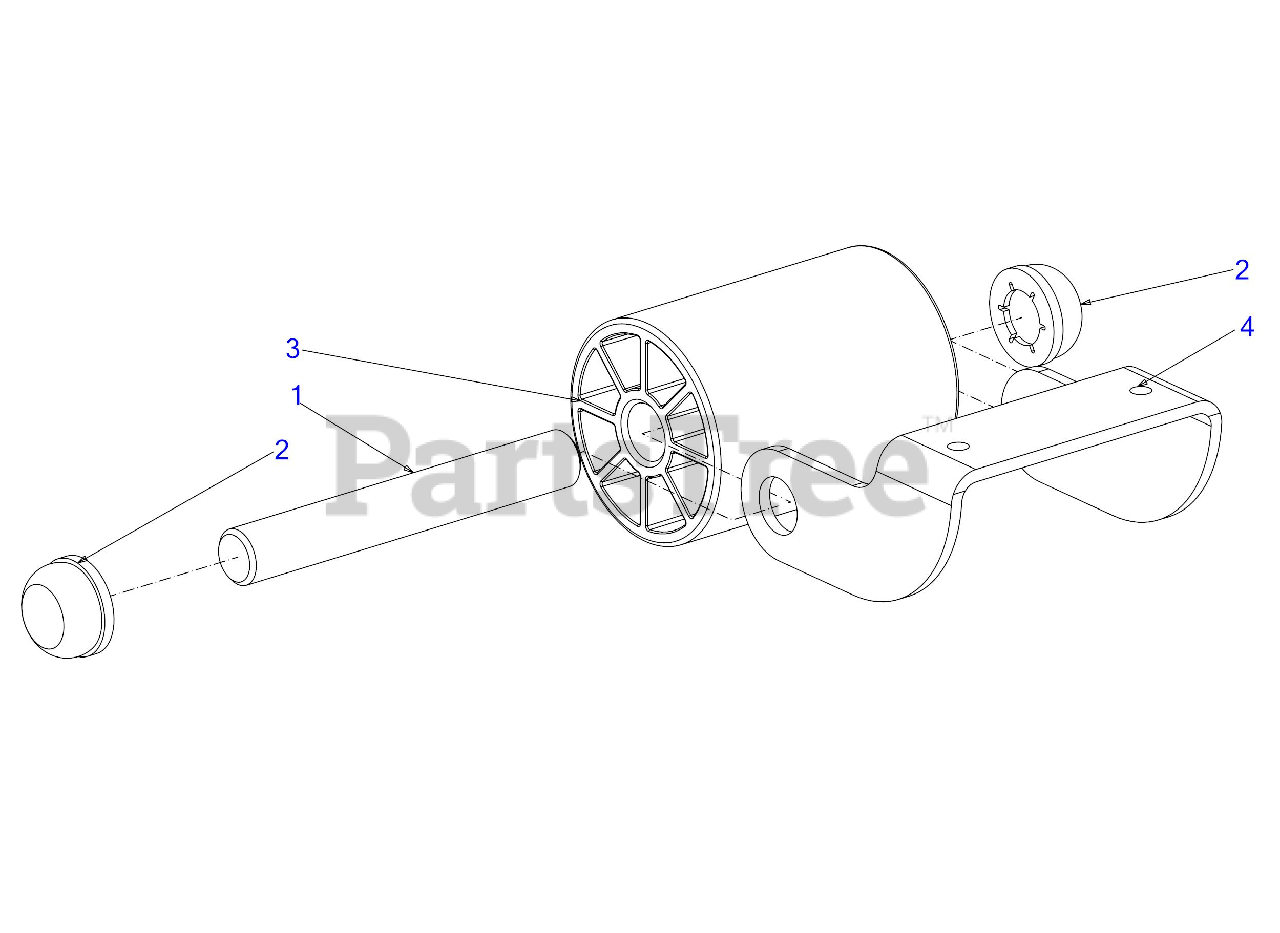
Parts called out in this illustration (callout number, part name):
1	ROLLER SHAFT .75 x 5.44
3	DECK ROLLER
4	ROLLER BRACKET
